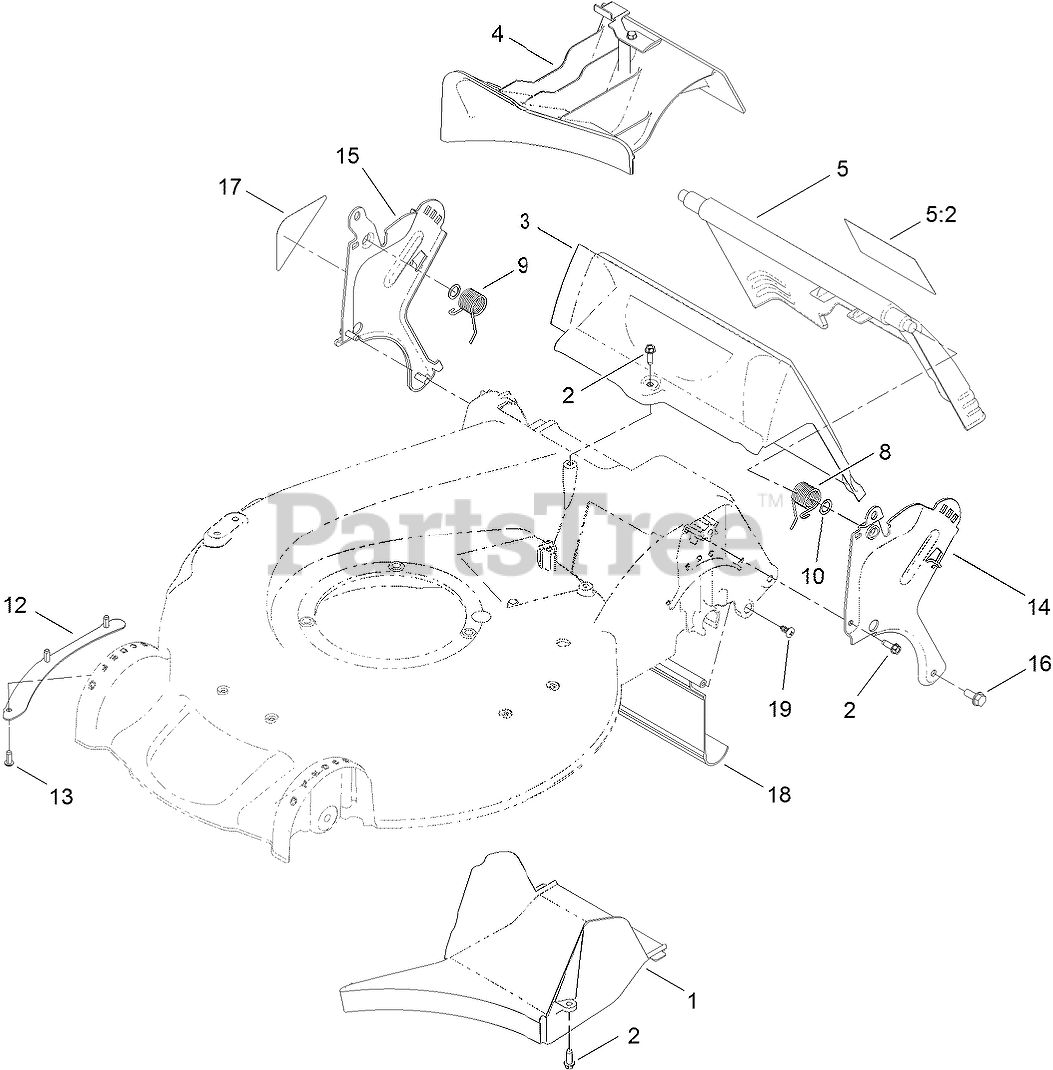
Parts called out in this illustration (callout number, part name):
1	TUNNEL-DISCHARGE
2	SCREW-HWHTF
4	MULCH PLUG ASM
5	REAR DOOR ASM
5:2	DECAL-WARNING
8	SPRING-TORSION
9	SPRING-TORSION
10	WASHER-NYLON
12	SHEET-LIP
13	SCREW
14	BRACKET-HANDLE, LH
15	BRACKET-HANDLE, RH
16	SCREW-HWHTF
17	DECAL-INSTRUCTION
18	SHIELD-TRAILING
19	SCREW-PTH
